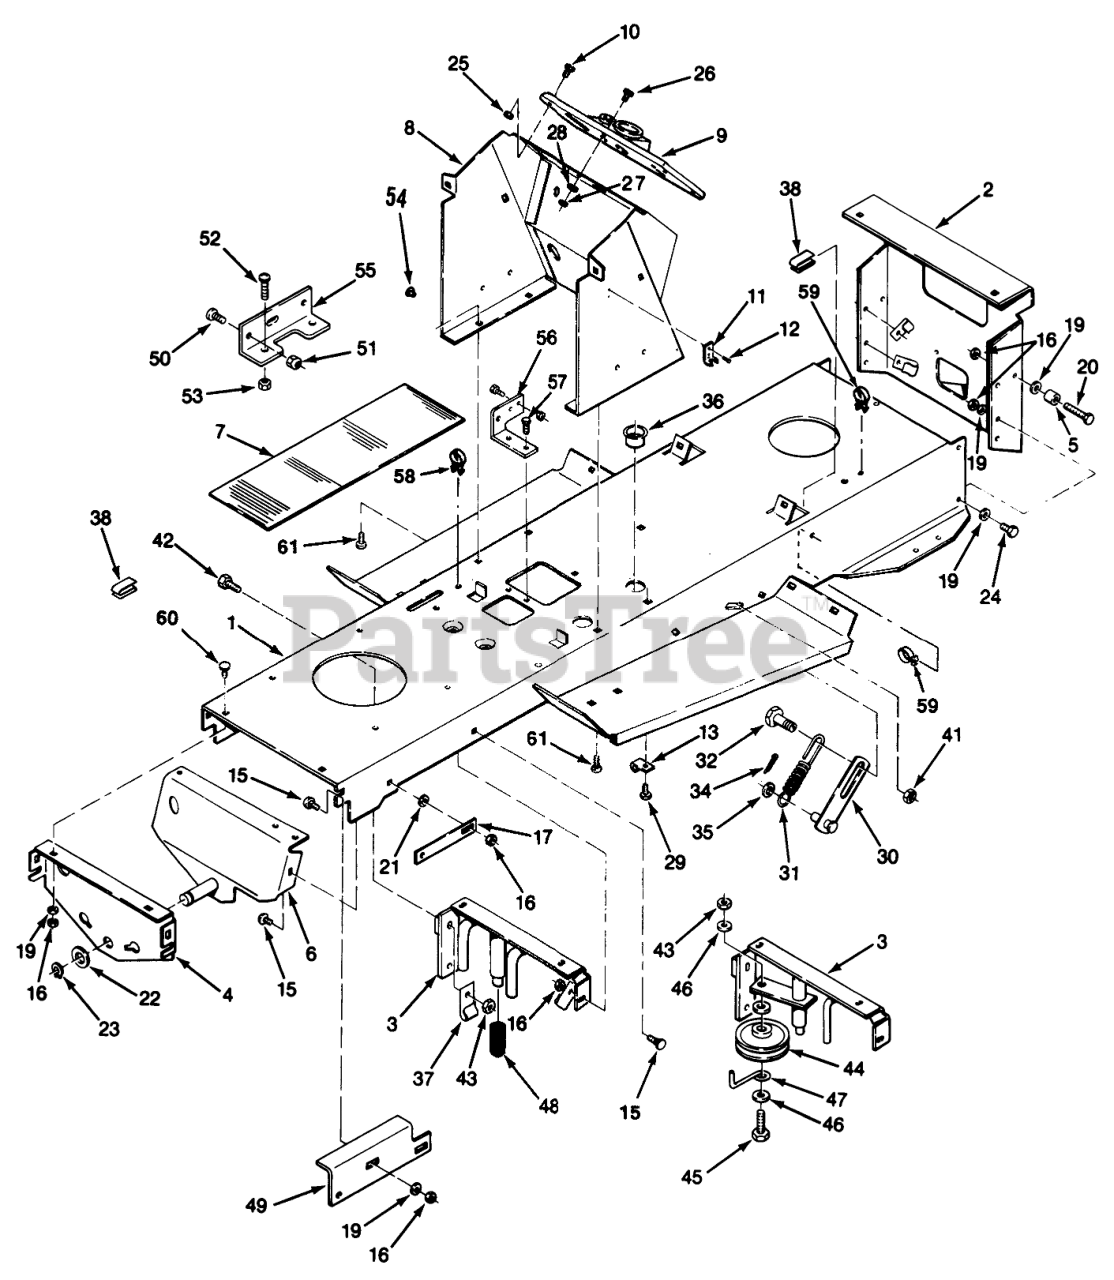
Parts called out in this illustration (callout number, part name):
1	FRAME R
2	PLATE-DRAWBAR R
3	ASS'Y-FRAME SUPPO R
4	PLATE SUPT - AXLE R
5	BEARING-CAM ROLLER
6	ASS'Y-AXLE SPT RE R
7	PAD-FOOTREST
8	WLDMENT-HOODSTAND B
9	CONSOLE
10	SCREW #10X.62 PHCR
11	KEEPER-LATCH
12	POPRIVET 1/8X 1/8 BK
13	J-CLIP
15	SCREW-CARR
16	NUT-LOCK, NI
17	STRAP R
18	Bolt
19	WASHER-PLAIN
20	SCREW-HH
21	WASHER-LOCK, INTERNAL
22	WASHER
23	RING-RETAINING
24	SCREW-HH
25	Nut
26	Screw
27	NUT-HEX
28	WASHER-LOCK
29	Bolt
30	ASSY LINK B
31	SPRING
32	CAM-ADJUST
34	PIN-COTTER
35	WASHER
36	BUSHING-NYLON 1.093
37	CLIP
38	RETAINER
40	Bolt
41	NUT-HEX, JAM
42	SCREW-HH
43	NUT-LOCK, NI
44	IDLER PULLEY R
45	SCREW-HH
46	WASHER-FLAT
47	RETAINER BELT R
49	BRACKET R.H. R
50	Screw
51	NUT-LOCK, NI
52	Screw
53	Nut
54	PLUG-NYLON .250
55	BRKT-FUSE HOLDER B
56	BRKT-SWITCH R
57	Screw-Machine
58	CLIP-SNAP IN
59	CLIP-SNAP IN
60	CARRIAGE BOLT -4
61	Bolt
